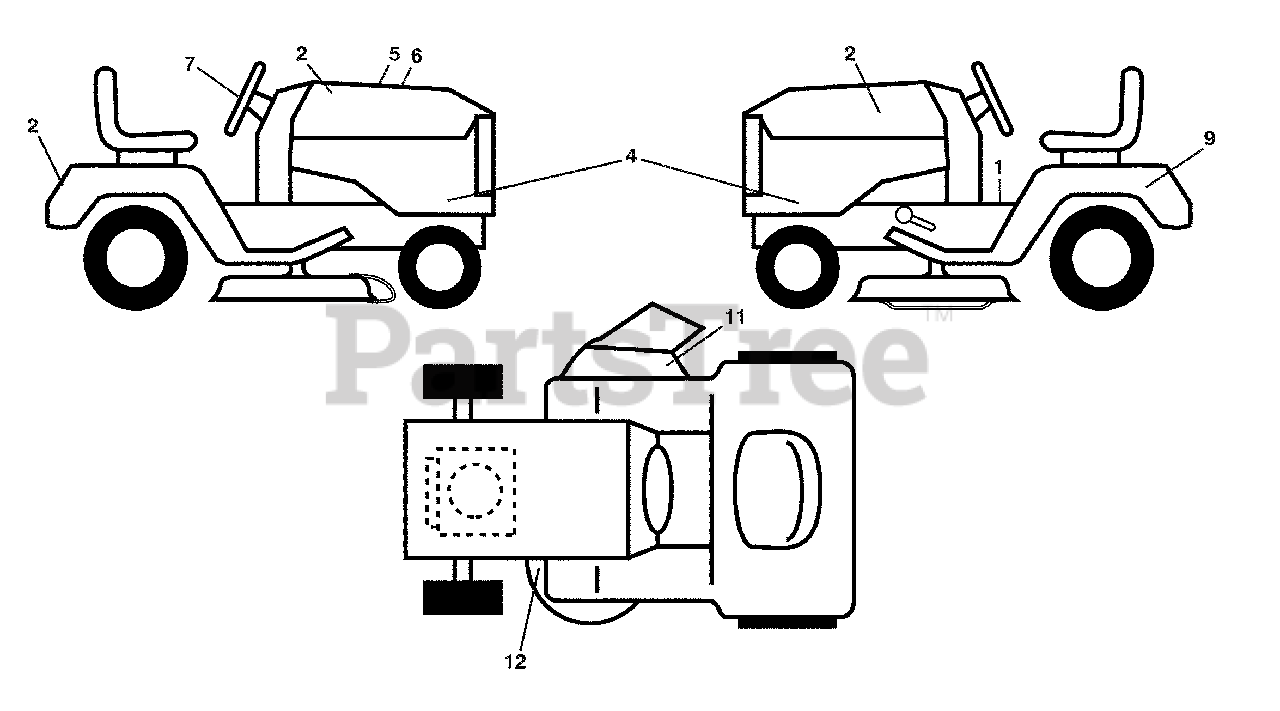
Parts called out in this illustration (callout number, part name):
1	Decal, Warning
2	Decal, Hood
4	Decal, Hood Panel
5	Decal, Customer Respons.
6	Decal, Replacement
7	Decal, Steering Wheel
9	Decal, Battery Dnge/Poi
11	Decal, Warning
12	Decal, Mower V-Belt Schematic
